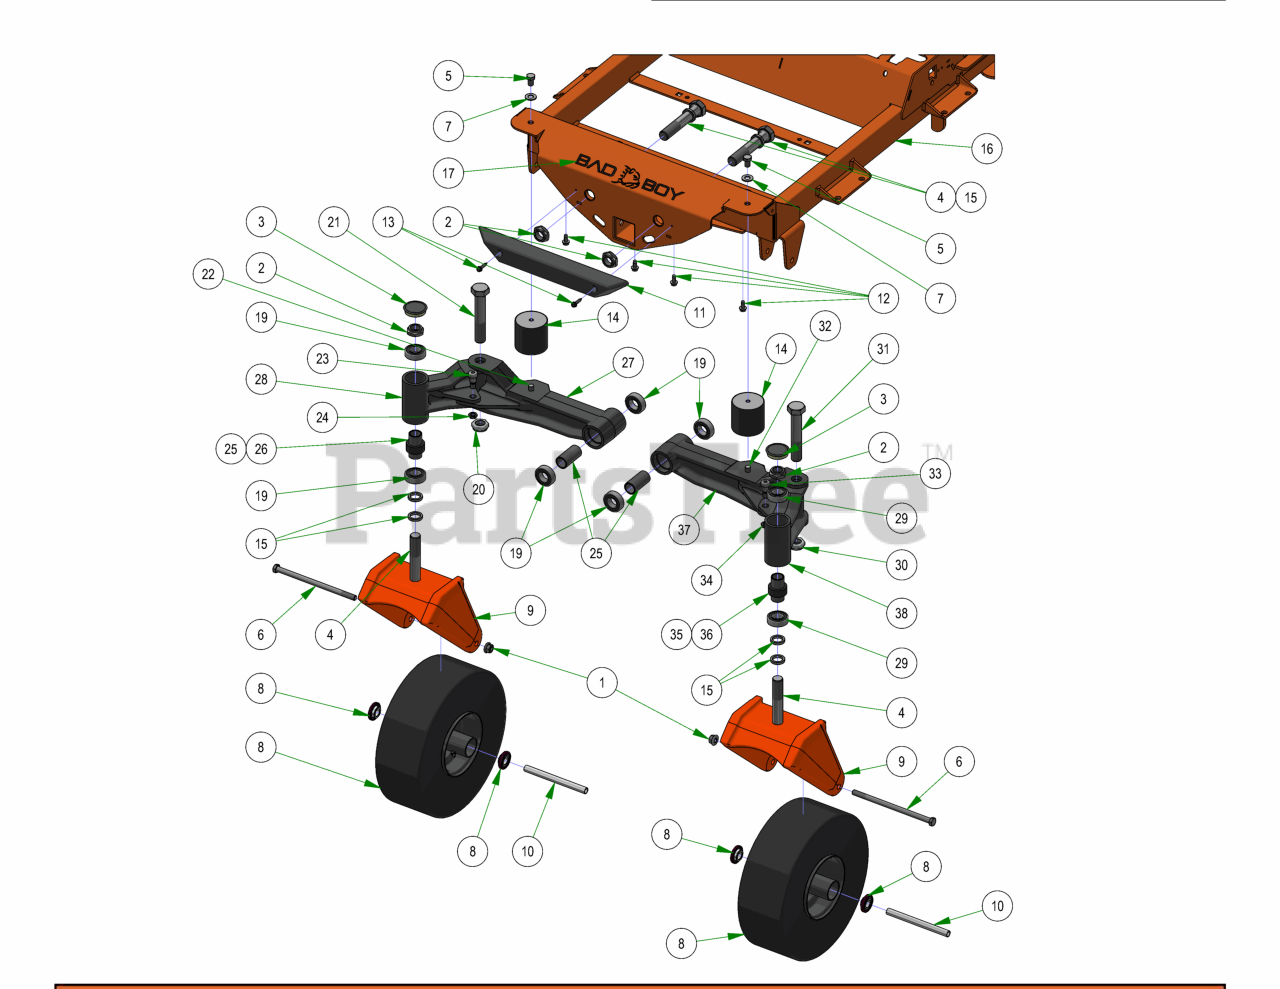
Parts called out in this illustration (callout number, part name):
1	1/2-13 NYLON INSERT FLANGE LOCKNUT ZINC
2	1"-14 NYLON INSERT JAM LOCKNUT ZINC
3	2017 Bearing Cover
4	1"-14 X 5-1/2 HEX CAP SCREW (GR.8) ZINC YELLOW
5	1/2-13 X 3/4 HEX CAP SCREW (GR.5) ZINC
6	1/2-13 X 9 HEX CAP SCREW (GR.5) ZINC
7	1/2 SAE FLAT WASHER (1-1/16" OD) GR.8 ZINC YELLOW
8	2019 15x6.00-6 Non Pneumatic Black Front Assembly
9	2020 R Series Cast Front Fork
10	Front Wheel Spanner
11	2017 XP BUMPER
12	5/16-18 X 3/4HEX WASHER SLOT (F) TCS ZINC
13	1/4-14 X 1-1/4 HEX WASHER UNSLOT TEK/3 ZINC
14	Vibration Mount-Blue Dot
15	1.02 ID X 1.38 OD X .250 THK SPACER ZINC
16	2019 Renegade Gas Frame - Powdercoated
17	Flying Bulldog Front Bumper Decal
18	Independetly Articulating Front Suspension Arms Patent Decal
19	1641 BEARING W/2 CONTACT RUBBER SEALS
20	1" Fine Thread 1/2 Nylock Nut
21	1"-14 X 5-1/2 HEX CAP SCREW (GR.8) ZINC YELLOW
22	1/2-13 x 1" Stud
23	5/8 X 5/8 SOCKET SHOULDER BOLT ZINC YELLOW
24	1/2-13 NYLON INSERT JAM LOCKNUT ZINC
25	2016 Front Bearing Spacer
26	Rubber Stabilizer (Front Forks) [R series]
27	61" & 72" Rogue Front Suspension Arm Inner RH
28	61" & 72" Rogue Front Suspension Arm Outer RH
29	1641 BEARING W/2 CONTACT RUBBER SEALS
30	1" Fine Thread 1/2 Nylock Nut
31	1"-14 X 5-1/2 HEX CAP SCREW (GR.8) ZINC YELLOW
32	1/2-13 x 1" Stud
33	5/8 X 5/8 SOCKET SHOULDER BOLT ZINC YELLOW
34	1/2-13 NYLON INSERT JAM LOCKNUT ZINC
35	2016 Front Bearing Spacer
36	Rubber Stabilizer (Front Forks) [R series]
37	61" & 72" Rogue Front Suspension Arm Inner LH
38	61" & 72" Rogue Front Suspension Arm Outer RH
